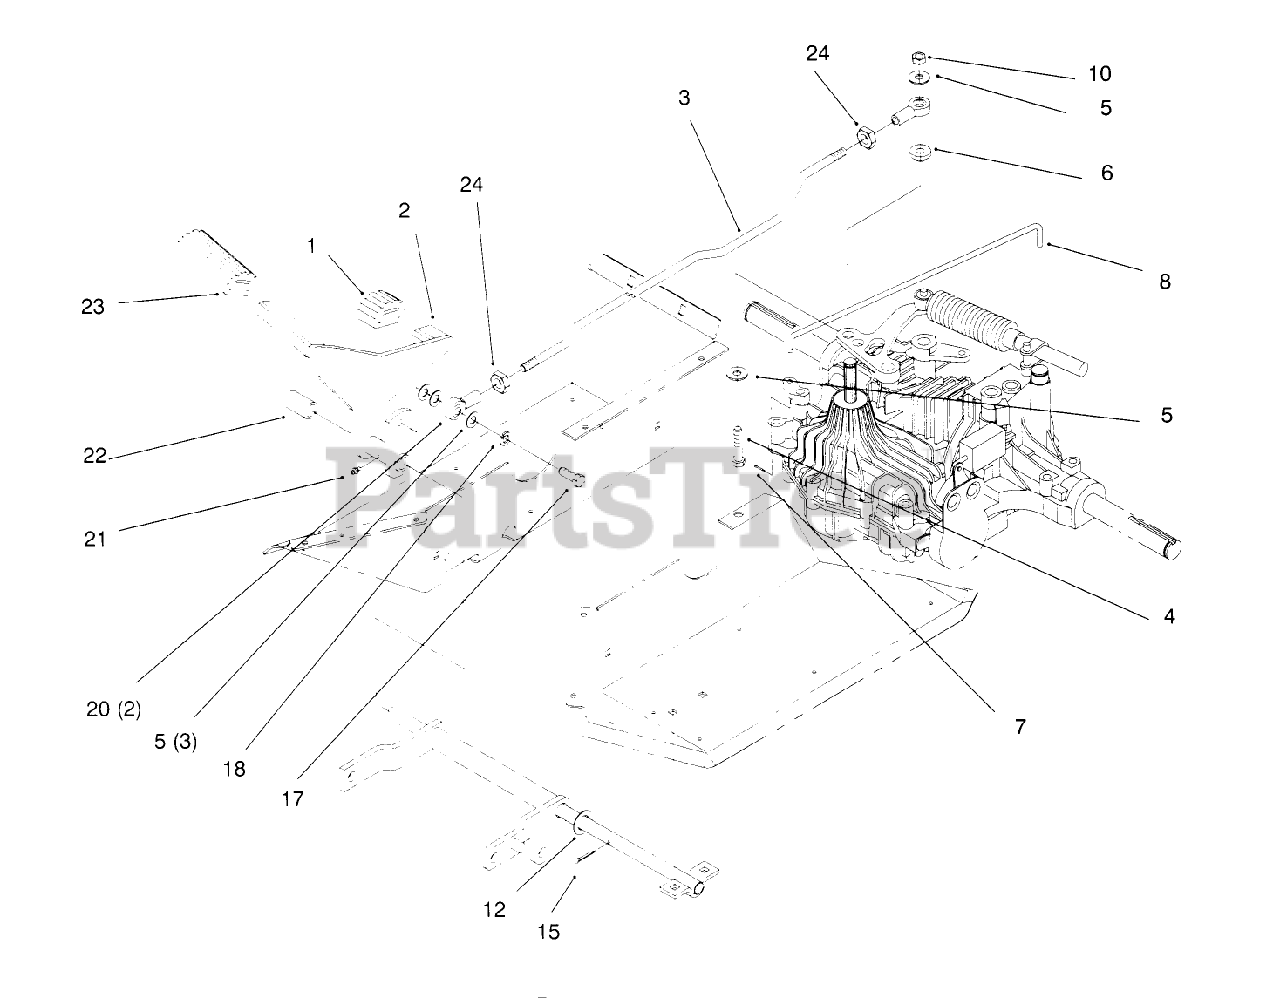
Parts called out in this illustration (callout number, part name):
1	PAD-PEDAL
3	ROD - HYDRO
4	SCREW-HH
5	WASHER-FLAT
6	BUSHING
7	PIN-COTTER
10	NUT-LOCK, NI
12	WASHER-FLAT
15	PIN-COTTER
17	SCREW-HH
18	WASHER-LOCK
20	END-ROD, FEMALE
21	FITTING-GREASE
22	SPACER
24	NUT-HJ
